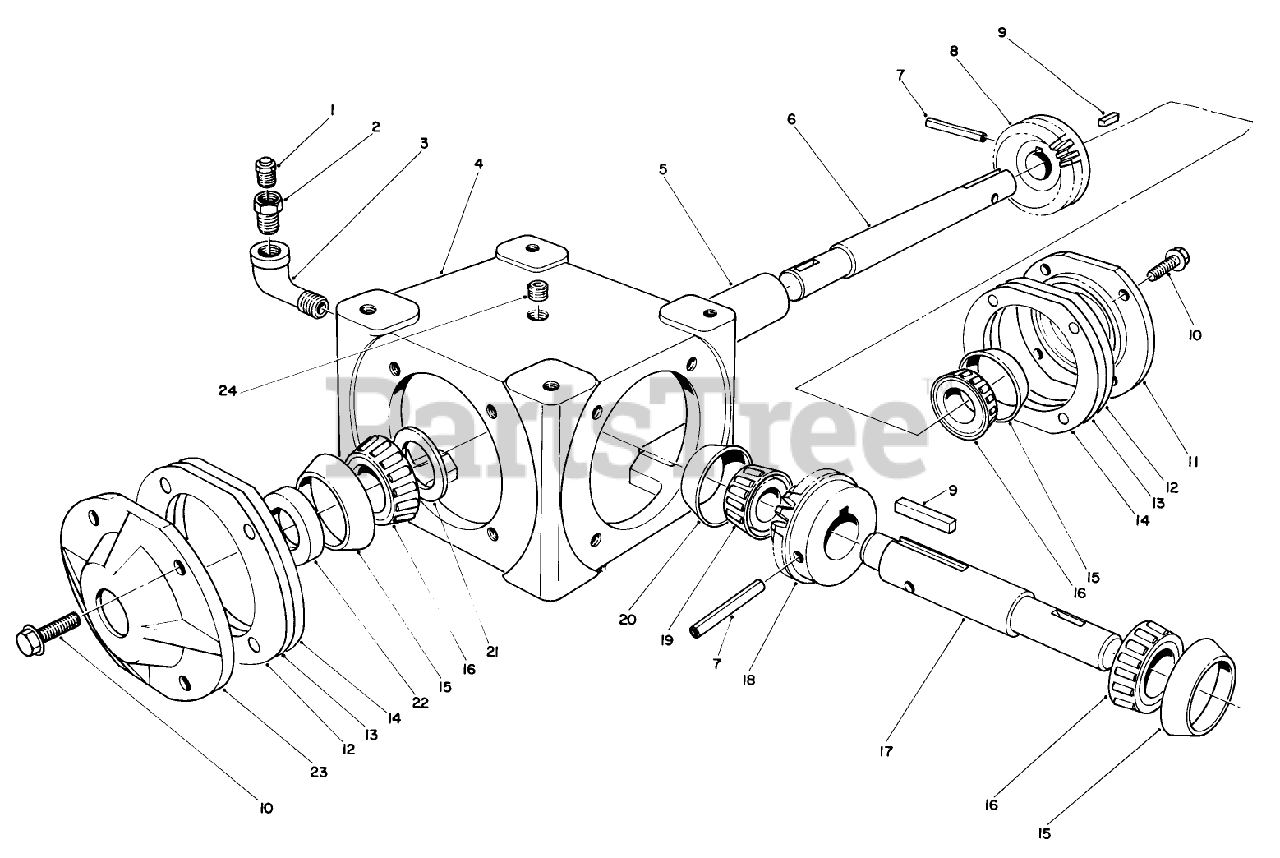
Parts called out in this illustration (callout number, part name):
1	Valve
2	BUSHING
3	Elbow-Street
4	HOUSING
5	SPACER
6	SHAFT
9	Key
10	SCREW-HH (OBS, C/R TO 3234-5)
12	GASKET
13	GASKET
14	GASKET
15	Cup
16	Cone
17	SHAFT
19	Cone
20	Bearing Cup
21	WASHER
22	Seal
24	PLUG (OBS, C/R TO 281-10)
